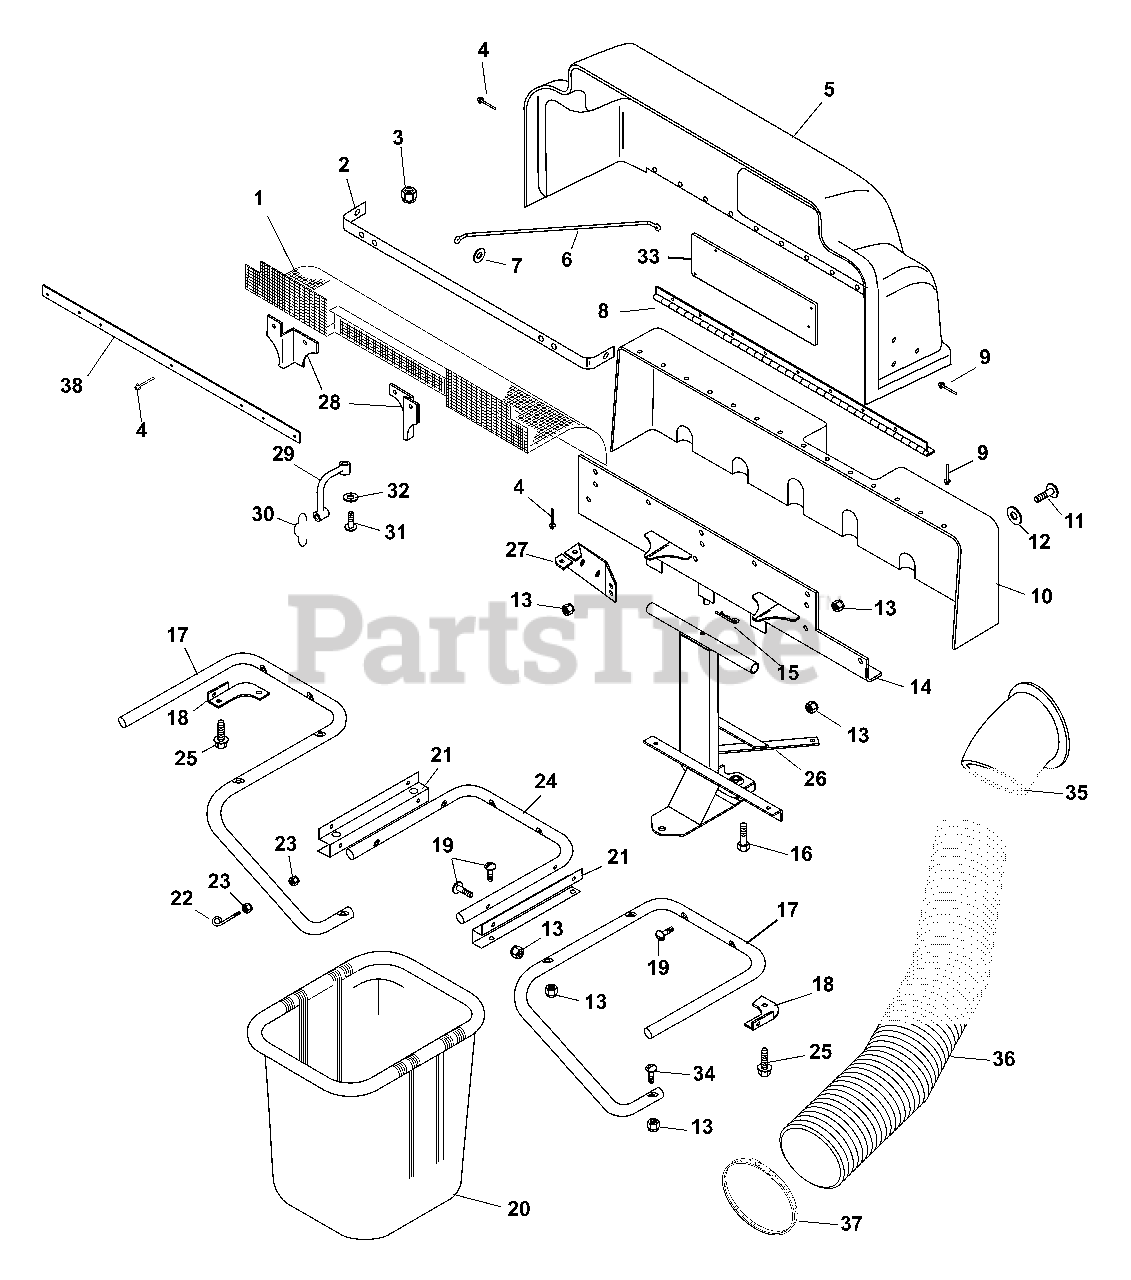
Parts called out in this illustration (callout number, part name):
2	SCREEN MOUNTING BRACKET
3	@NUT-LK-NYL 10-24 W/INSRT YWZC
4	RVT-POP.187X.527 DOME ST
5	HINGED COVER W/DECALS
7	@WSHR-FL-STL .188X.438X.049 YZ
8	HINGE- 2.0"X35.0"
9	RVT-POP .187X.402 DOME ST
10	STATIONARY COVER
11	@BLT-HEX .31-18X.75 GR5 YWZC
12	@WSHR-FL-STL.38X.875X.083 YWZC
13	@NUT-LK-CTR .31-18 YWZC
14	MOUNTING BRACKET
15	PIN-HAIR INT .08X.38X1.42 YWZC
16	@BLT-HEX .50-13X1.25 GR5 YWZC
17	RIGHT TUBE
17	LEFT TUBE
18	RH CORNER BRACKET
18	LH CORNER BRACKET
19	SCR-MCH .31-18 X 1.50 YWZC
20	GRASS BAGGER BASKET
21	TUBE BRACKET
22	EYEBOLT
23	@NUT-LK-CTR .25-20 YWZC
24	CENTER TUBE
25	@SCR-TAP .31-18X.50 HWH TR YWZ
26	BAGGER FRAME
28	BAFFLE LH
28	BAFFLE RH
29	BATTERY STRAP
31	@SCR-MCH 10-24X1.00 HWH YWZC
32	@WSHR-FL-STL.219X.50X.049 YWZC
34	@SCR, .31-18X2.0 FL SKT HD YZC
35	BAGGER BOOT - UPPER
36	HOSE 7 X 35
37	CLAMP-HOSE WRM 2.13/8.62X.56
38	GUARD - SCREEN
